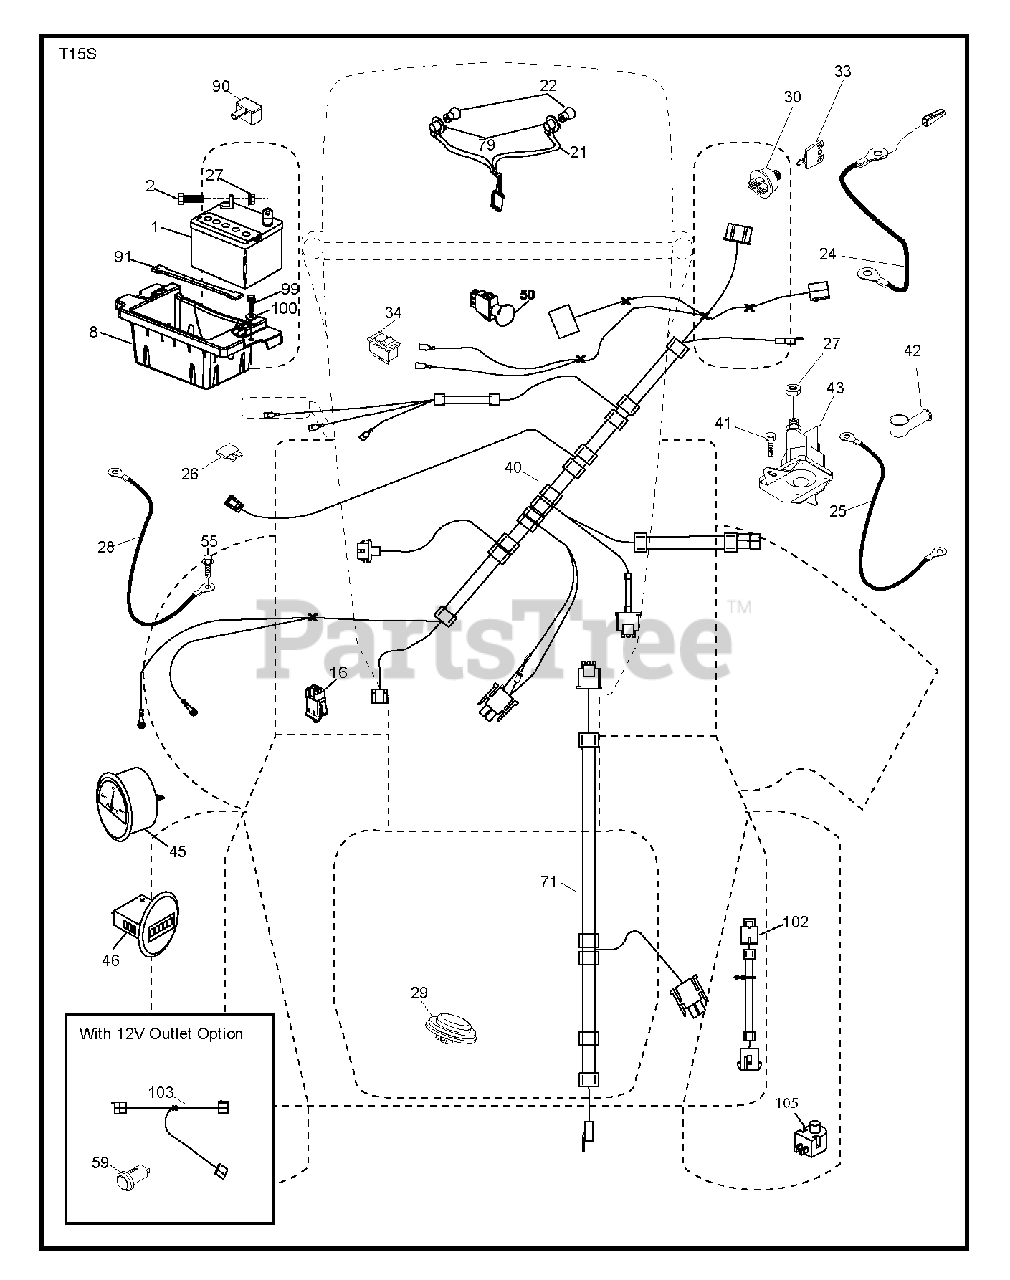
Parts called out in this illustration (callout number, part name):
1	Battery, Dry 30 Amp
2	BOLT.HEX.1/4.X.3/4.DICHROMATE
8	BOX.BATTERY.MOUNT.FRONT.LT
16	SWITCH INTERLOOK PUSH-IN
21	HARNESS.LIGHT W/4152J BULBS
24	CABLE.BATT.POS.WIRE.TG.DA SOL
25	CABLE.STARTER.6G.BL/RED.17.5
26	FUSE 20AMP
27	NUT
28	CABLE GROUND 6 GA 21" 90T BLK
29	SWITCH.SEAT.DELTA.OPC.
30	SWITCH.IGN.DELTA.W.LGH.ROS
33	KEY.CHAIN.BLISTER.PACK.GEN.INT
40	HARNESS IGN. DASH
41	SCREW
42	TERMINAL COVER
43	SOLENOID.W/BRASS.PLUNGER
45	AMMETER GAUGE ROUND SNAP-IN
46	HOURMETER.GAUGE.RNK.SNAPIN.LS
50	RB PTO.SWITCH.8 TERMINAL.BLACK
55	SCREW 5/16"
59	OUTLET.12-VOLT
71	HARNESS-CHASSIS SUB
79	BULB HOLDER ASM.
90	COVER.TERMINAL.BATTERY
91	STRAP.BATTERY.MOUNT.FRONT(2 2)
99	SCREW HEXWSHR 1/4-20X3/4
102	HARNESS PIGTAIL PCH TEX ROS
103	HARNESS.PIGTAIL.12V.OUTLET.
105	REVERSE SWITCH
